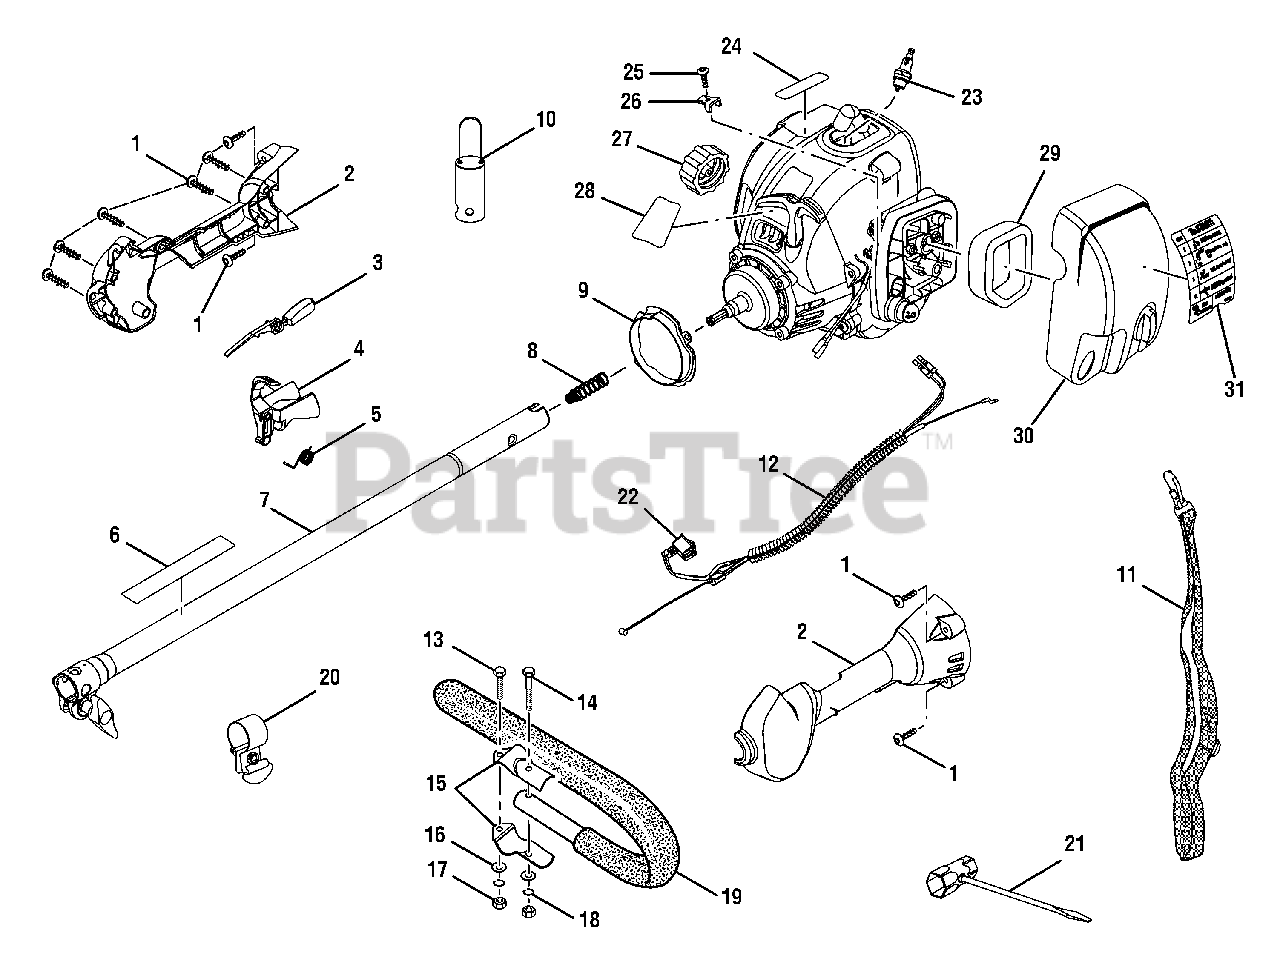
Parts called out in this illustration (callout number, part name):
1	SCREW (10-14 X 1 in. T.F. TRUSS HD.)
2	HANDLE ASSEMBLY
3	TRIGGER LOCK
5	TORSION SPRING
6	WARNING LABEL
7	BOOM ASSEMBLY (INC. KEY NO. 6)
8	COMPRESSION SPRING
9	RING GUARD
10	STORAGE END CAP
11	SHOULDER STRAP
12	THROTTLE AND LEAD ASSEMBLY
13	BOLT (1/4-20 X 1 in. HEX HD.)
14	BOLT (1/4-20 X 1-1/2 in. HEX HD.)
15	HANDLE BAR CLAMP
16	WASHER
17	HEX NUT (1/4-20)
18	LOCK WASHER
19	J HANDLE AND GRIP
20	STRAP HANGER
21	COMBINATION WRENCH
22	SWITCH (MOMENTARY CONTACT)
23	SPARK PLUG (CHAMPION RCJ6Y OR NGK BPMR7)
24	LOGO PLATE
25	SCREW
26	THROTTLE CABLE CLIP
27	FUEL CAP ASSEMBLY
28	MODEL LABEL
29	AIR FILTER
30	AIR BOX COVER
31	STARTING/PRIMER LABEL
